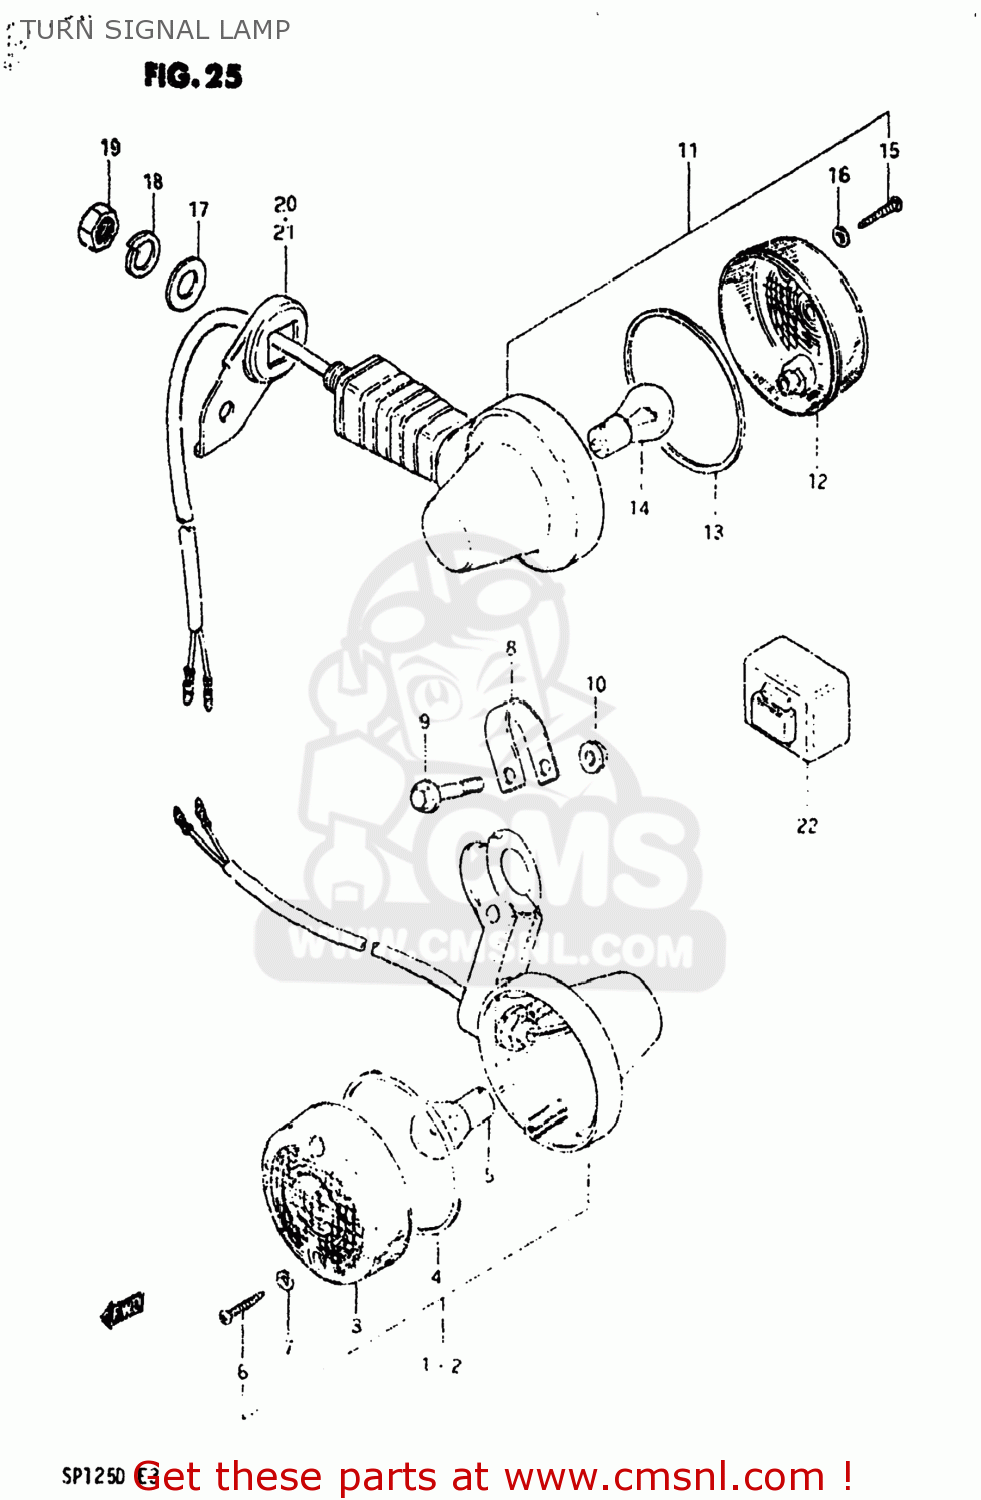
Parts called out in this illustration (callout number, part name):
1	LAMP ASSEMBLY,FRONT TURN SIGNAL
2	LAMP ASSEMBLY,FRONT TURN SIGNAL
3	LENS
4	GASKET (NAS)
5	BULB(6V17W,STANLEY,A4513A)
6	SCREW TAPP.
7	GASKET (NAS)
8	PLATE
9	BOLT 5X42
10	NUT
11	LAMP ASSEMBLY,REAR TURN SIGNAL
12	LENS
13	GASKET (NAS)
14	BULB(6V17W,STANLEY,A4513A)
15	SCREW TAPP.
16	GASKET (NAS)
17	WASHER
18	WASHER,LOCK 12
19	NUT
20	BRACKET,REAR TURN SIGNAL
21	BRACKET,REAR TURN SIGNAL
22	RELAY,TURN SIGNAL
